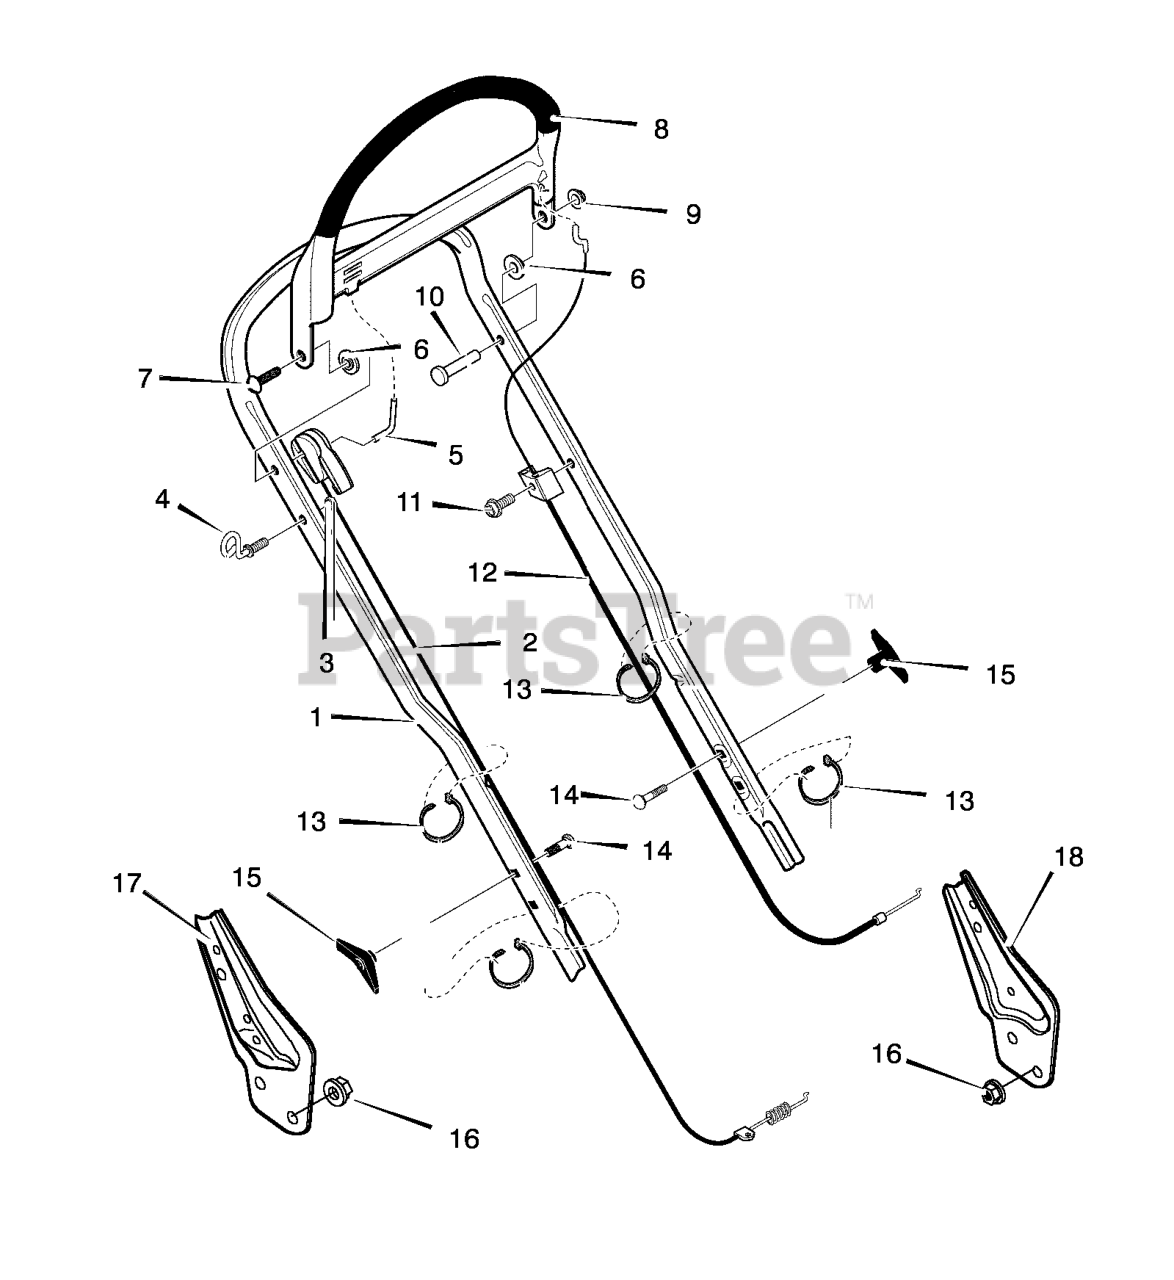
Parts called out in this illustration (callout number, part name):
1	Handle, Upper
2	Control, Drive
3	Locknut
4	Guide, Rope
5	Rod, Drive Link
8	Lever, Stop
9	Push- On Cap
10	Pin, Clevis
12	Cable, Stop
13	Strap, Tie
14	Bolt, Carriage
15	Wingnut
16	Nut
17	Bracket, Right Handle
18	Bracket, Left Handle
